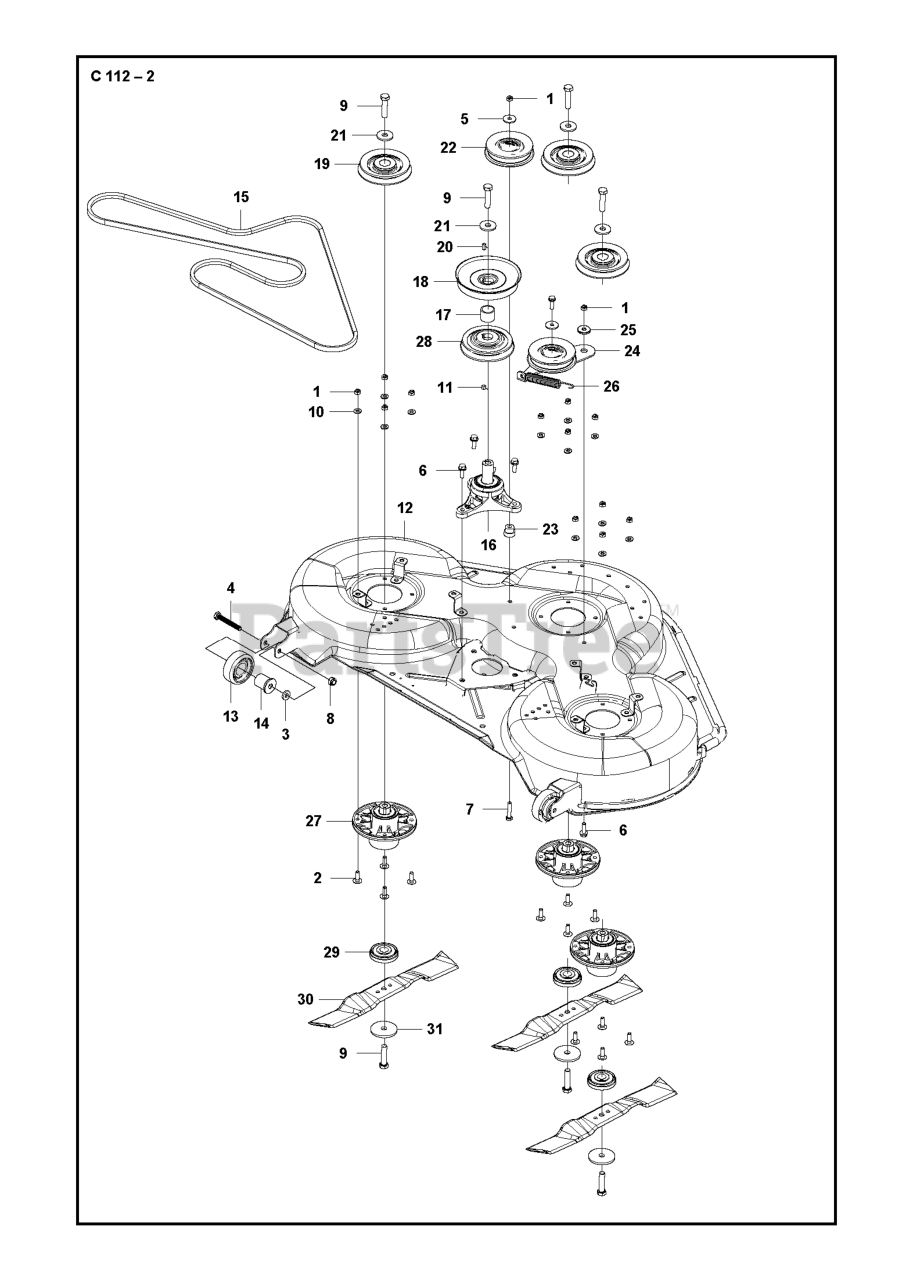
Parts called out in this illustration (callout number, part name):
1	LOCKNUT M8
6	BOLT
10	WASHER BRB 8.4X17
25	WASHER PLASTIC ASSY
